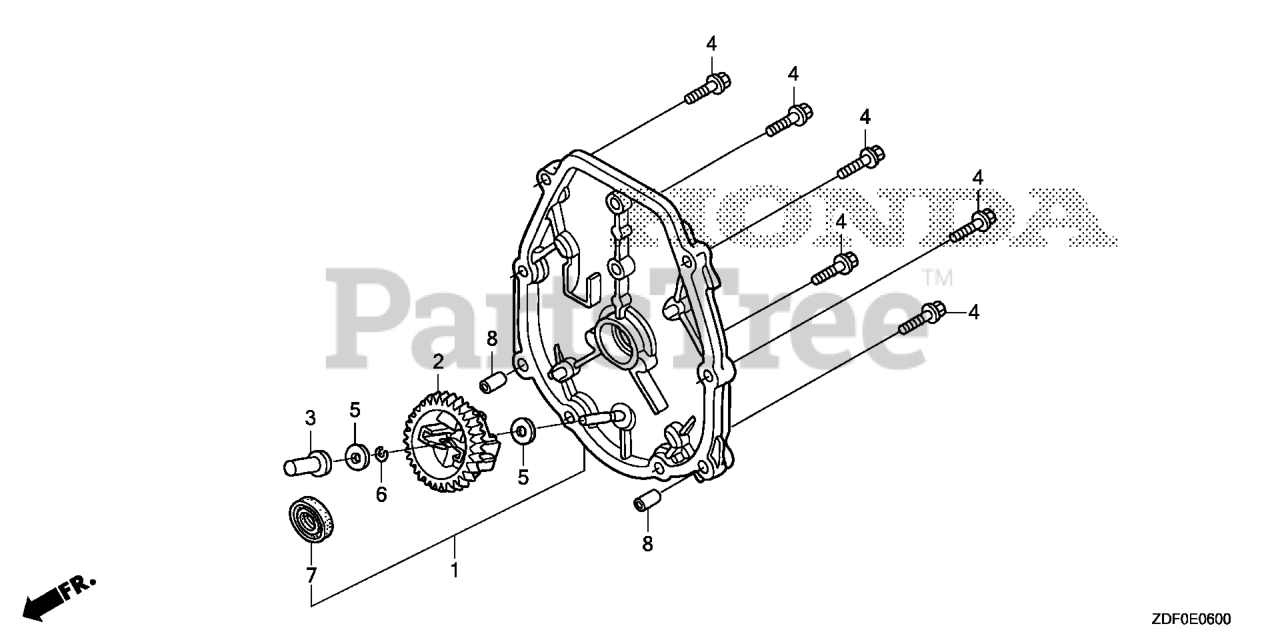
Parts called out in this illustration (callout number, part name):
1	COVER, CRANKCASE SIDE
2	GOVERNOR ASSY.
3	SLIDER, GOVERNOR
4	BOLT, FLANGE (5X23)
5	WASHER (4.2X13)
6	CLIP, GOVERNOR HOLDER
7	OIL SEAL (17X27X5) (KOYO)
8	PIN A, DOWEL (6X10)
